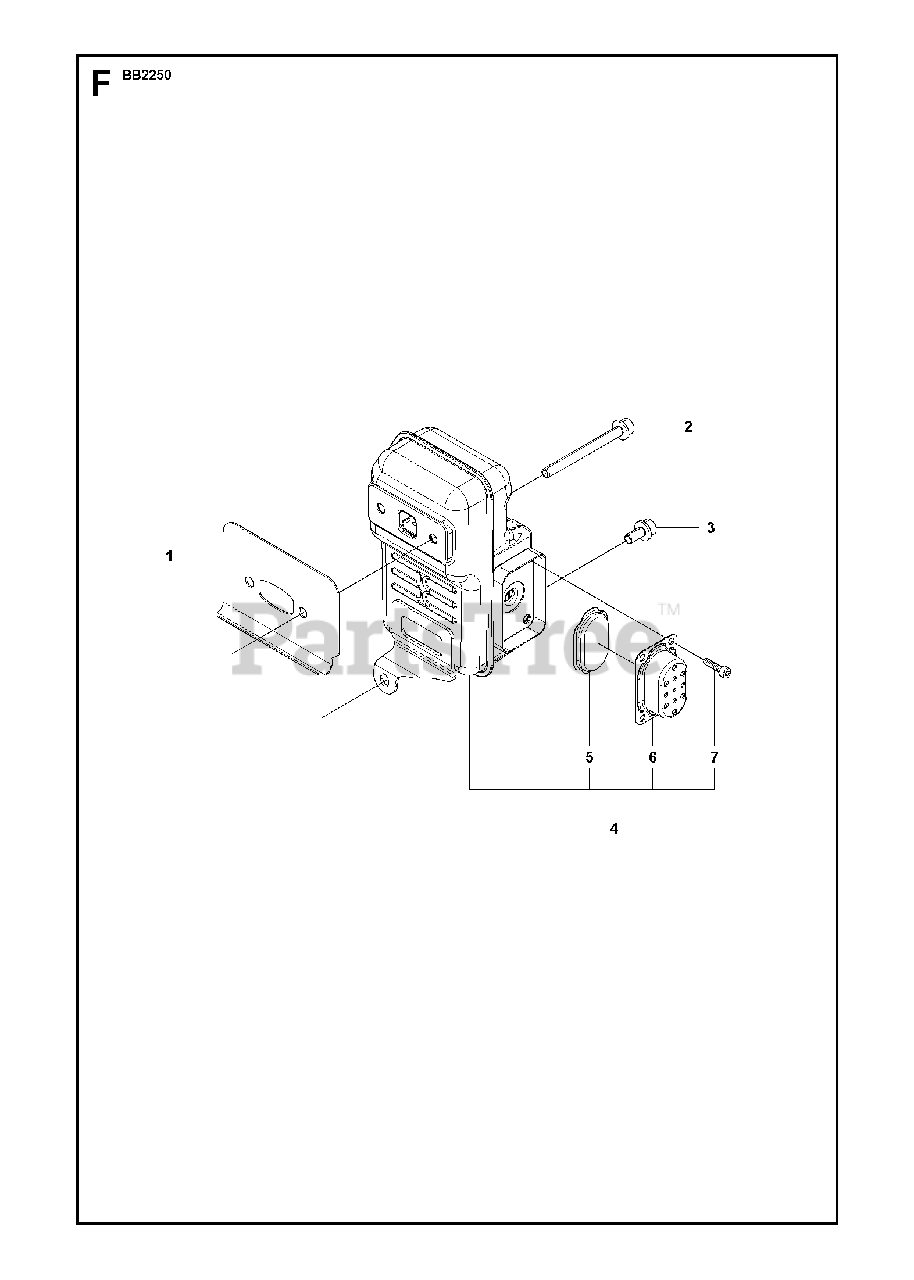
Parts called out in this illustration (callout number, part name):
4	MUFFLER ASSY
5	SPARK ARRESTOR SCREEN
6	EXHAUST DUCT
7	BOLT
